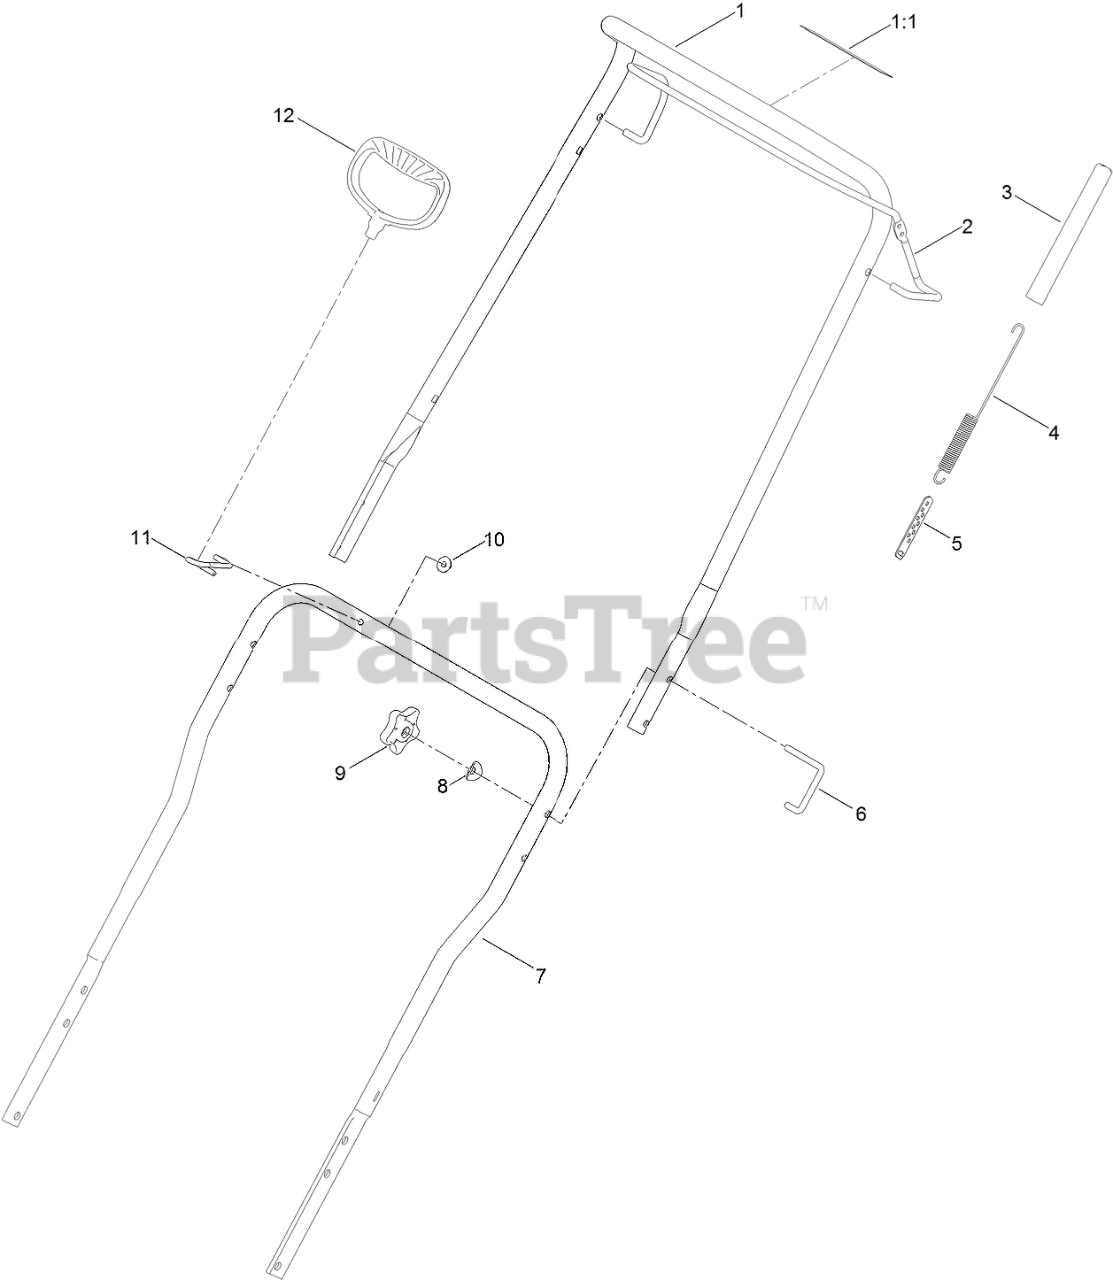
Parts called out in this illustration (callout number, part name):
1	UPPER HANDLE ASM
1:1	DECAL-DRIVE, ROTOR
2	BAIL-CLUTCH
3	COVER-SPRING
4	SPRING-EXTENSION, CLUTCH
5	ADJUSTER-CABLE, CLUTCH
6	LOCK-HANDLE
7	HANDLE-LOWER
8	WASHER
9	KNOB-HANDLE
10	NUT-HF
11	GUIDE-ROPE
12	HANDLE-RECOIL
